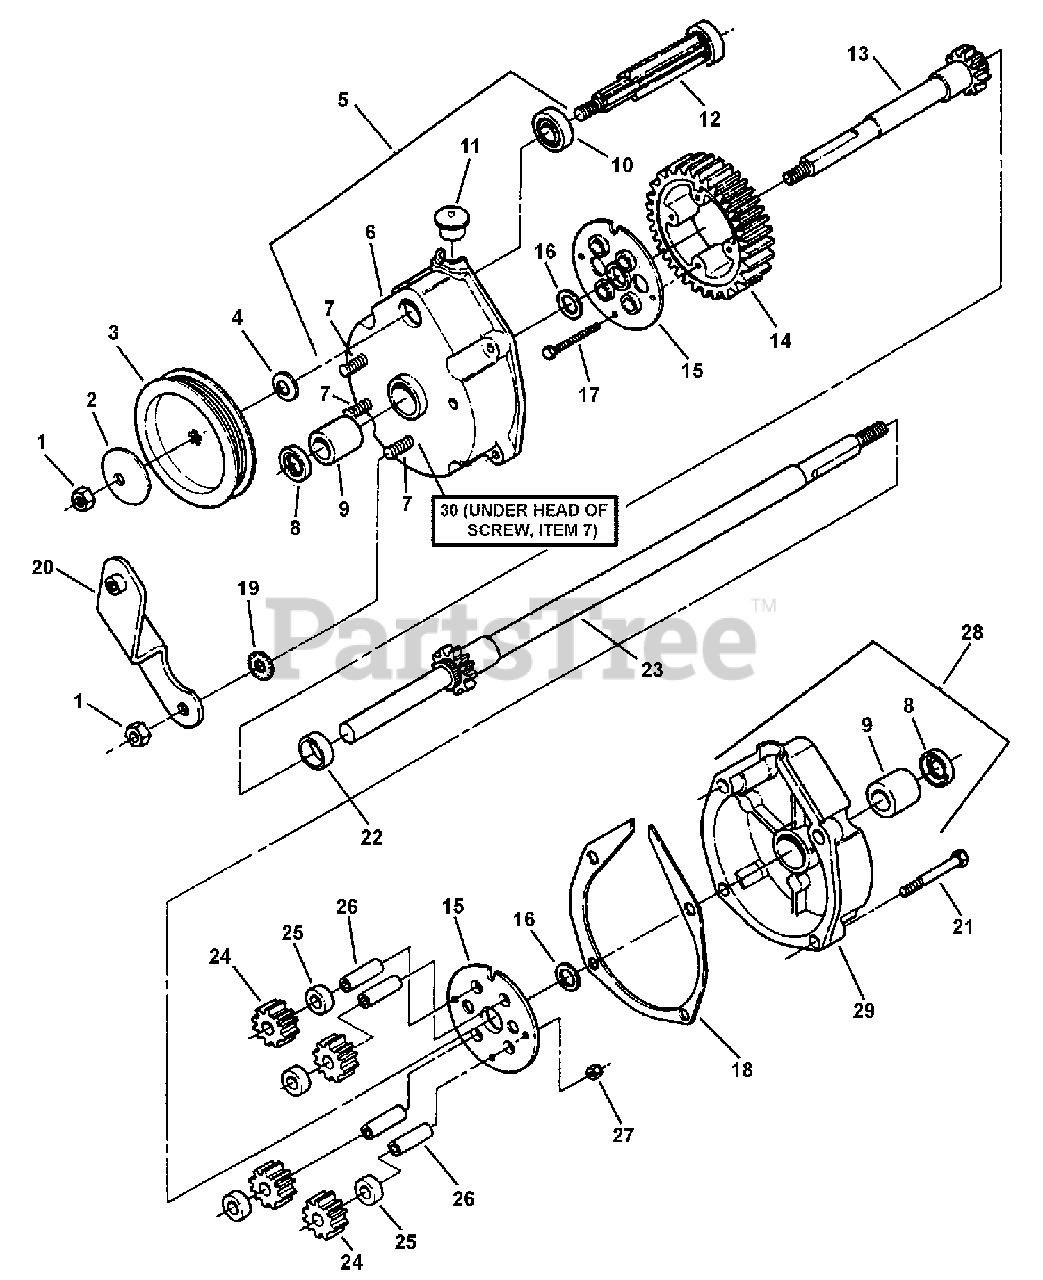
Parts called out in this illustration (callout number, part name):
1	NUT, 5/16-24 Hex Lock, GR C
2	WASHER, Cone
3	PULLEY, Poly-Vee Belt
4	WASHER, Spring
5	ASSEMBLY, Housing Right
6	HOUSING, Right Side
7	SCREW, 5/16-24 x 1-1/8" Rib Neck, GR5
8	SEAL, 5/8" Internal Dia.
9	BEARING, Tapered- (Differential Housing)
10	BEARING, Ball, .437 I.D. x 1.125 O.D. x .375 Thk.
11	PLUG, Housing
12	GEAR, Input
13	ASSEMBLY, Short Axle
14	GEAR, Differential (46 tooth)
15	PLATE, 46T Gear
16	WASHER, Thrust, 3/4" I.D.
17	SCREW, #10-32 x 1-1/2" Hex Head Cap GR5
18	GASKET, Housing
19	WASHER, 5/16" Internal/External Tooth Lock
20	BRACKET, Differential
21	SCREW, 1/4-20 x 1-1/4" Hex Washer Self-Tap
22	SPACER, Axle Gear
23	ASSEMBLY, Long Axle
24	GEAR, Pinion (12 tooth)
25	SPACER, Pinion Gear
26	SHAFT, Pinion
27	NUT, #10-32 Hex Nyloc
28	ASSEMBLY, Housing Left
29	HOUSING, Left
30	GASKET,5/8" O. D.
